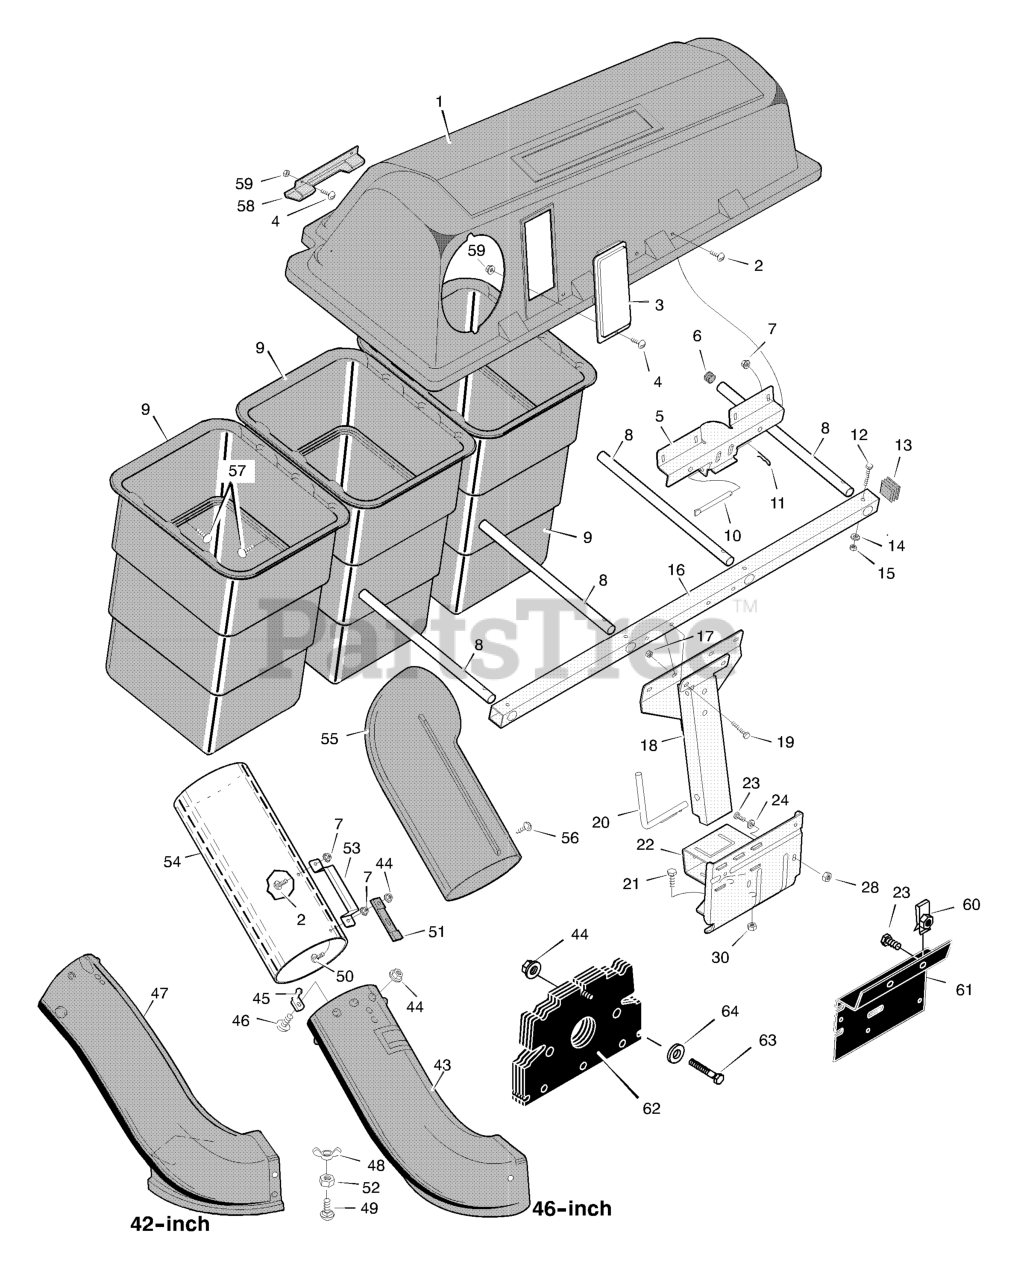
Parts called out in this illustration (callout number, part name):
1	Cover, Bagger
5	Hinge, Bracket
7	Nut, Hex
8	Tube, Container
9	Container
10	Pin, Cover Hinge
11	Pin, Hair
13	Plug
14	Lockwasher
16	Tube, Support
17	Nut
18	Assembly, Channel
20	Pin, Channel Mount
21	Bolt, Hex
22	Assembly, Bagger Mount
23	Bolt, Hex
28	Nut, Super Flange
30	Nut, Hex
43	Extension, Chute 46
44	Locknut, Flange
45	Pin, Latch
46	Bolt, Carriage
47	Extension, Chute 42
48	Wingnut
49	Bolt, Carriage
51	Latch, Rubber
53	HANDLE, Connect Tube
54	Tube, Connecting
57	Fastener, Panel
58	Handle, Plastic
59	Nut, Hex
61	Bracket, Adapter
62	Weight, Front
